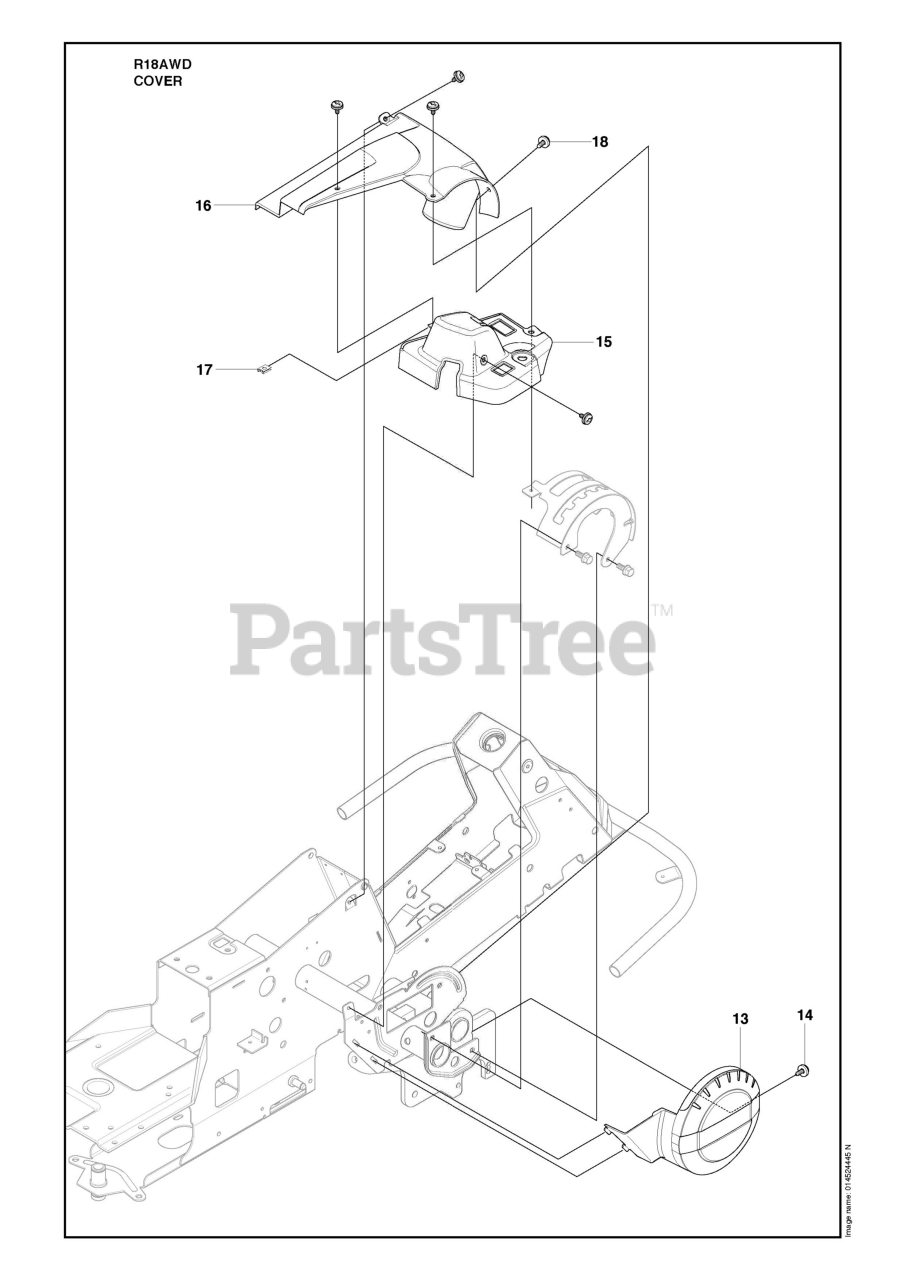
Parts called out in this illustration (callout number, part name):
1	FOOT PLATE
3	FOOT PLATE
6	ENGINE HOOD ASSY
10	ENGINE HOOD ASSY
13	CONTROL COVER
15	CONTROL COVER
19	COVER
26	PROTECTIVE COVER
27	CLIP GRAY
28	UNIT COVER
